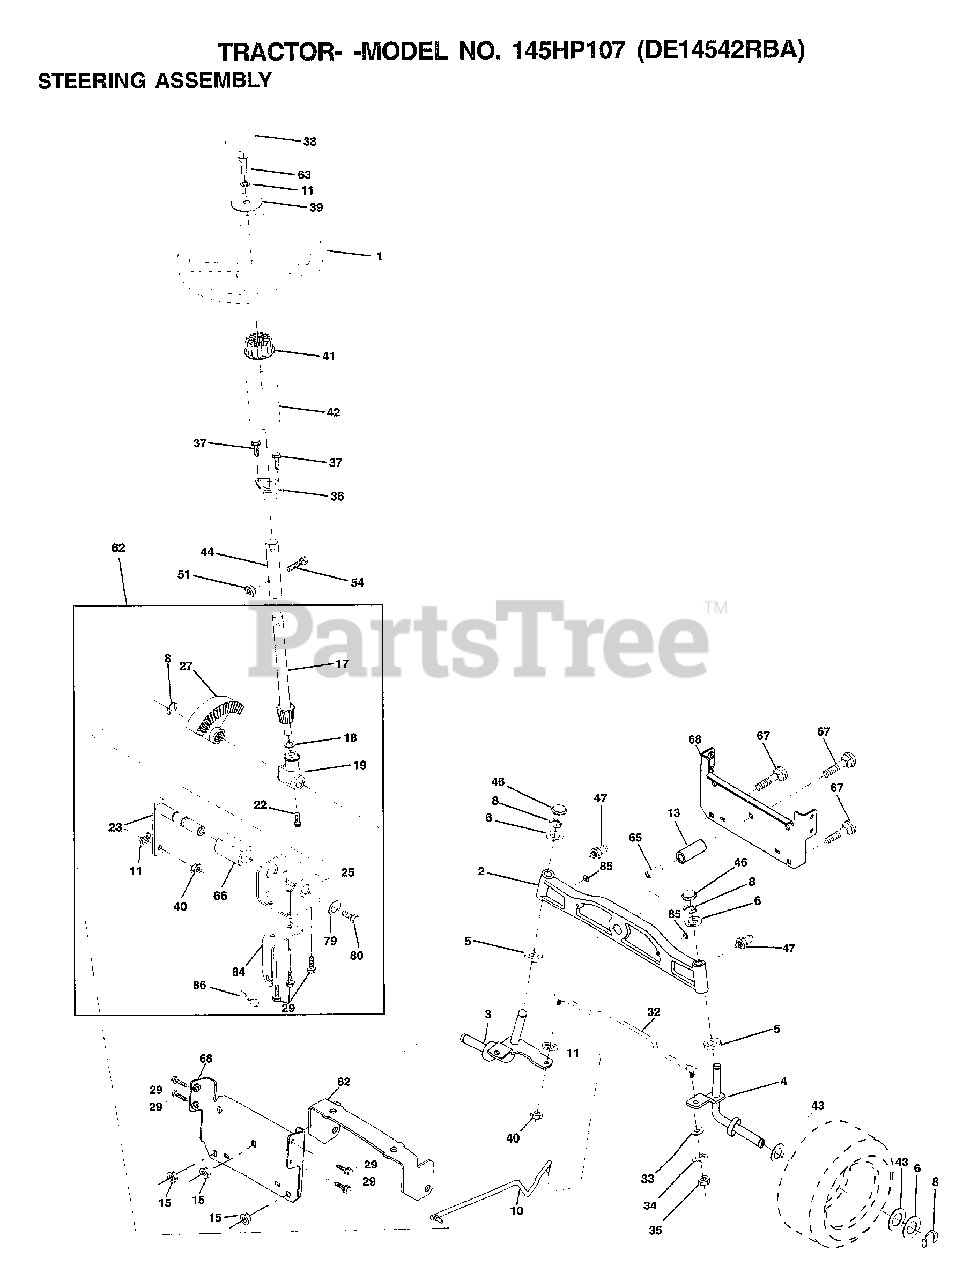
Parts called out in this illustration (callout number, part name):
2	AXLE ASM CAST IRON LT
3	SPINDLE ASM
4	SPINDLE ASM
5	WASHER .T
6	WASHER
8	RING
10	LINK DRAG
11	LOCKWASHER
13	SPACER BEARING
15	NUT.HXFLG.LOCK.
17	SHAFT ASM STEERIN
18	THRUST WASHER
19	SUPPORT.SHAFT.STEER
22	SCREW.HX.WSH.HD
23	SHAFT.ASM.PITMAN
25	BRKT-STEERING
27	GEAR SECTOR
29	SCREW
32	TIE ROD
33	WASHER M
34	LOCKWASHER
35	NUT.LOCK.5/16-24
36	BUSHING.STEERING
37	"SCREW-TT,10-32 FL"
38	CAP WHEEL STEER
39	WASHER
40	GRIPCO NUT
41	ADAPTER LT
42	BOOT.STEERING.DASH.P/L
43	WASHER
44	EXT SHAFT STEERIN
46	CAP
47	ZERK M
51	NUT
54	BOLT
62	KIT.STEER.ASM
63	BOLT
65	"SPACER BRCAE,AXLE"
66	"BEARING-ARM,PITMA"
67	BOLT RDHD 3/8-16
68	BRACE AXLE
79	WASHER
80	BOLT.HX.NYLON3/8-16X3/
82	METER HOUR
84	BRACKET CABLE CLUTCH CHASSIS
85	XMAS TREE FASTNER
86	RETAINER SPRING
